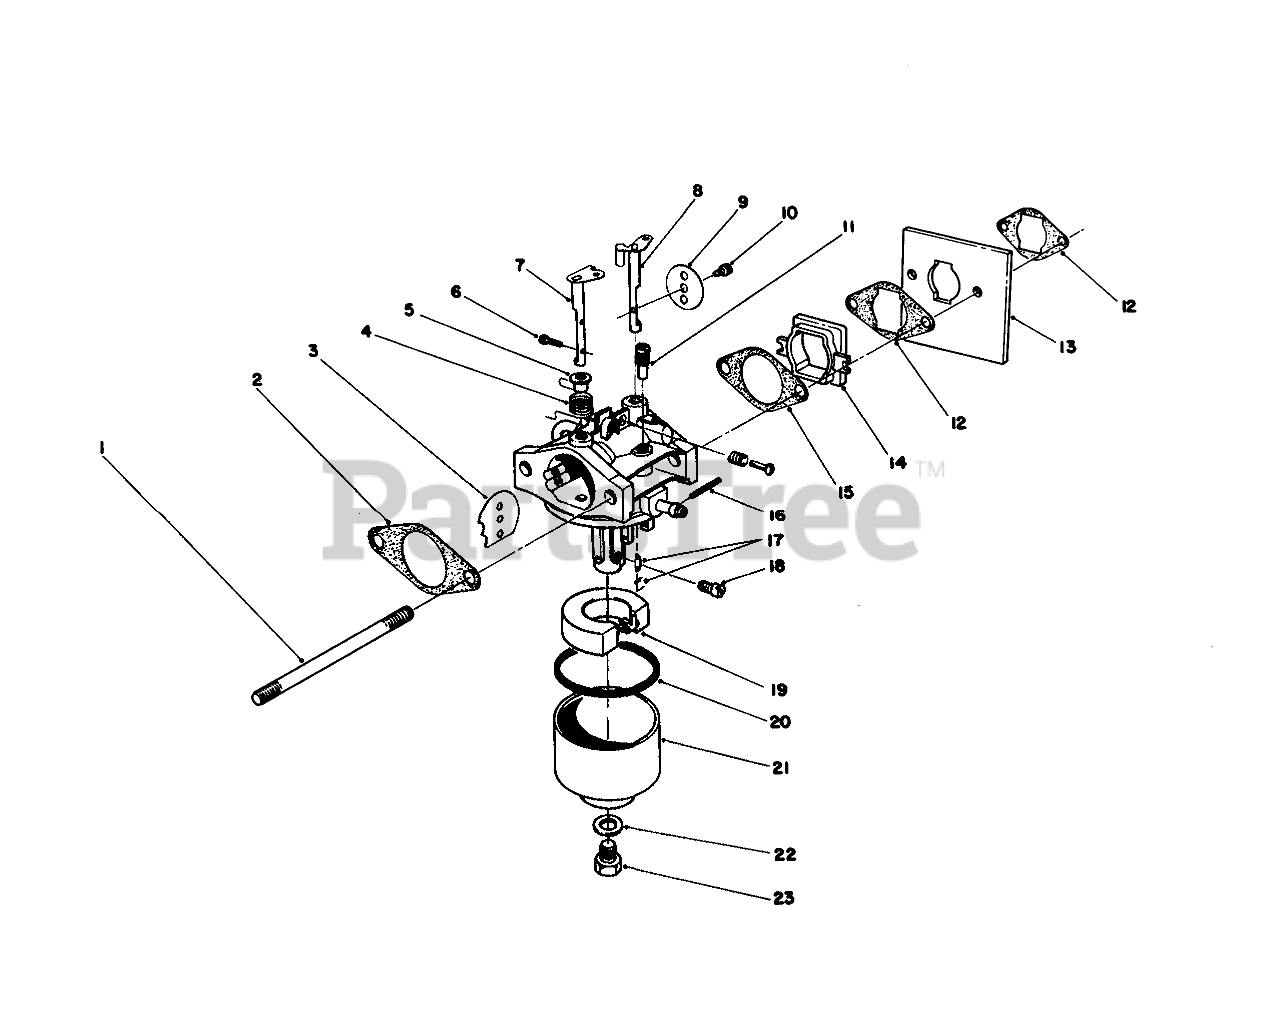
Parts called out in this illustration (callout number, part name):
1	CARB STUD BOLT
2	GASKET-AIR CLEANER
3	CHOKE VALVE
4	SPRING
5	BUSHING
6	SCREW
7	SHAFT-CHOKE
8	SHAFT
9	PLATE
10	Screw-Throttle
11	PILOT JET
12	GASKET
13	SHIELD
14	INSULATOR
15	GASKET-CARB
16	Pin
17	NEEDLE
18	MAIN JET (76.3)
19	FLOAT
20	GASKET
21	Bowl-Float
22	GASKET
23	Bolt
